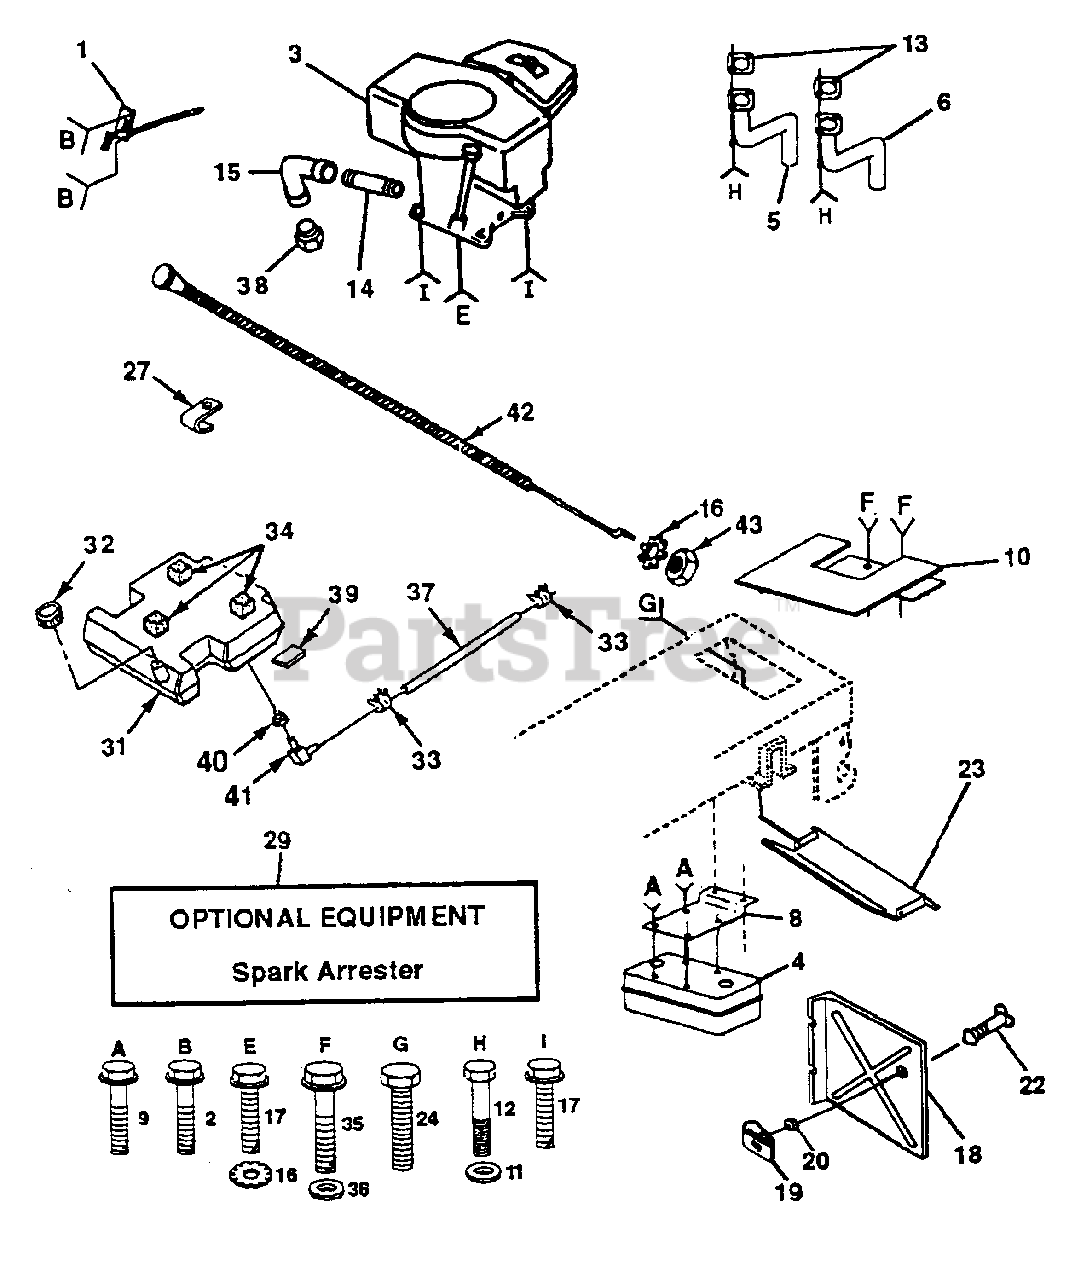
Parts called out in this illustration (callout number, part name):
1	Control RH Blk Flg 37 88
2	Screw Hex Thd Cut 1/4-20x5/8 T
4	Muffler LT B&S
5	Tube Manifold LH
6	Tube Manifold RH
8	Bracket Muffler Mounting
9	Screw Hex Wsh Thd Cut 1/4-20
10	Shield Heat LT
11	Washer Lock Hvy Hlcl 1/4 (Order from Engine Manufacturer)
12	Bolt, Fin Hex 1/4-20 x 3/4 (Order from Engine Manufacturer)
14	Nipple Pipe 3/8 Npt X 4-1/2"
15	Elbow Std 90 Degree 3/8-18 Npt
16	Washer Lock Ext Tooth 3/8
17	Screw Thdrol 3/8-16 x 1-1/2
18	Shield Heat Mech
19	Receptacle 1/4 Turn
20	Retainer 1/4 Turn
22	Stud 1/4 Turn
23	Shield Heat Browning LT/YT
24	Screw Tap Hex #10-24unc X 1/2
27	Clip, Fuel Line
29	Kit Spark Arrestor (Flat Scrn)
31	Tank Fuel 3 50 Rear
32	Cap Asm Fuel W/sym Vented
33	Clamp Hose Blk
35	Screw Thdrol 5/16-18 x 3/4
36	Washer 13/32 x 1-1/4 x 14 Ga.
37	Line Fuel 54"
40	Bushing
41	Stem Tank Fuel
42	Choke Control
43	Nut, Fin Hex 3/8-24 Unf
